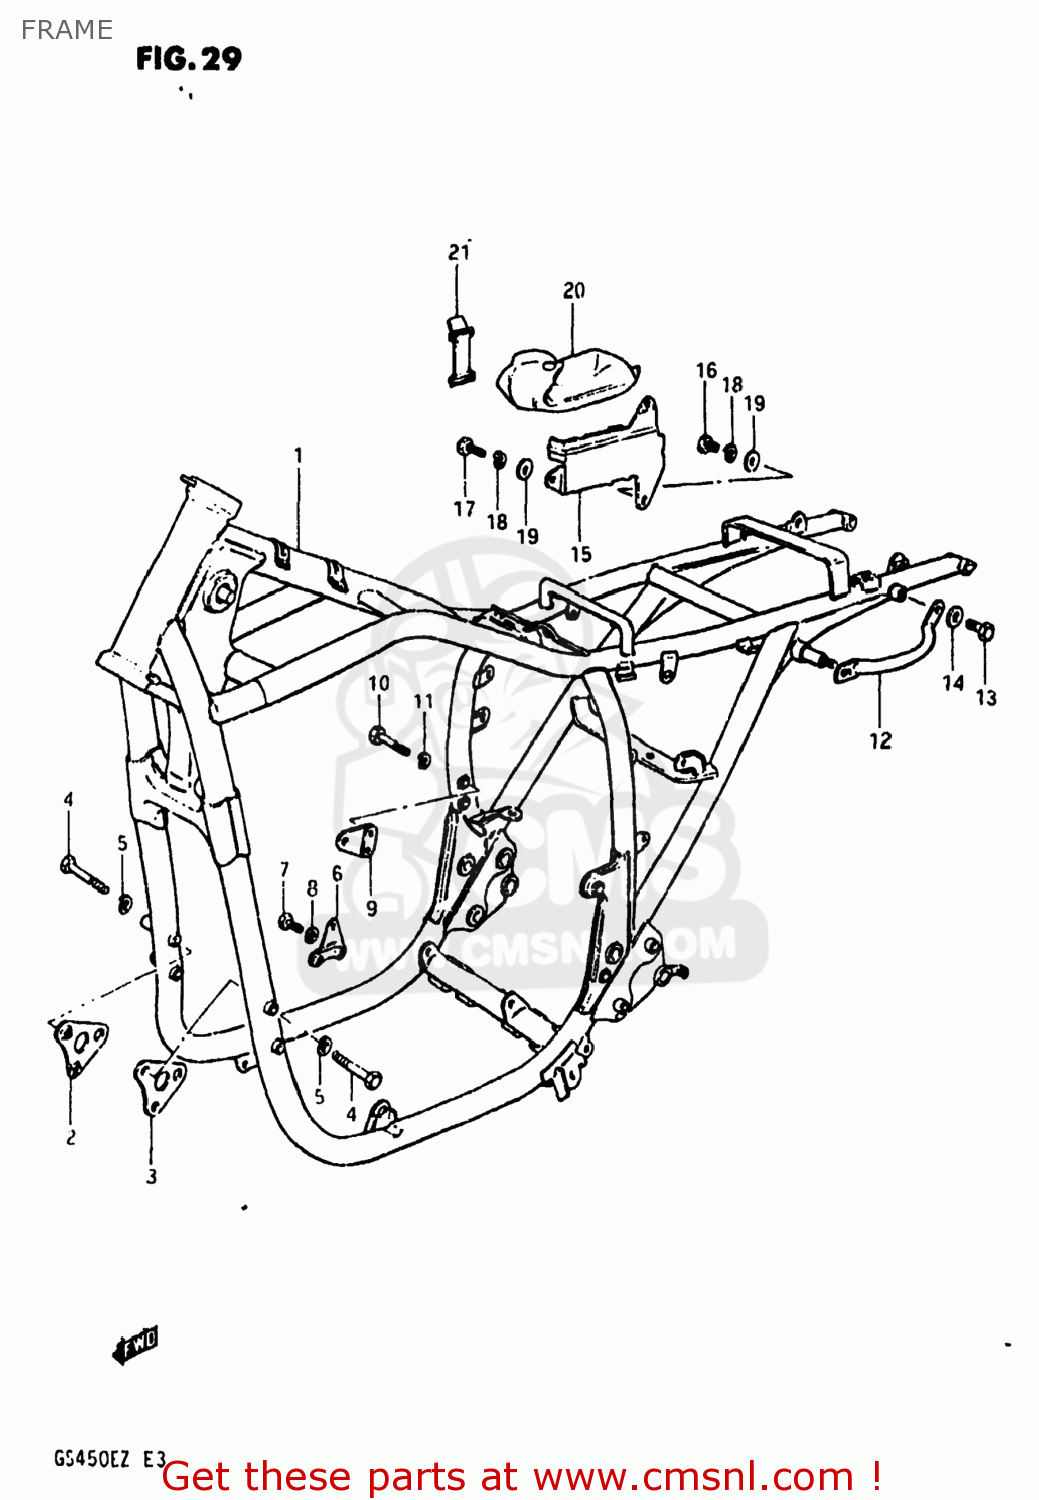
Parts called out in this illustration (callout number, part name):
1	FRAME
2	PLATE,ENGINE MOUNTING
3	PLATE,ENGINE MOUNTING
4	BOLT
5	LOCK WASHER
6	PLATE,ENGINE MOUNTING
7	BOLT
8	LOCK WASHER
9	PLATE,ENGINE MOUNTING
10	BOLT 8X45
11	LOCK WASHER
12	GRIP,FRAME HANDLE
13	BOLT
14	WASHER
15	HOLDER,TOOL
16	SCREW 6X12
17	SCREW
18	LOCK WASHER
19	WASHER
20	TOOL SET
21	BAND
